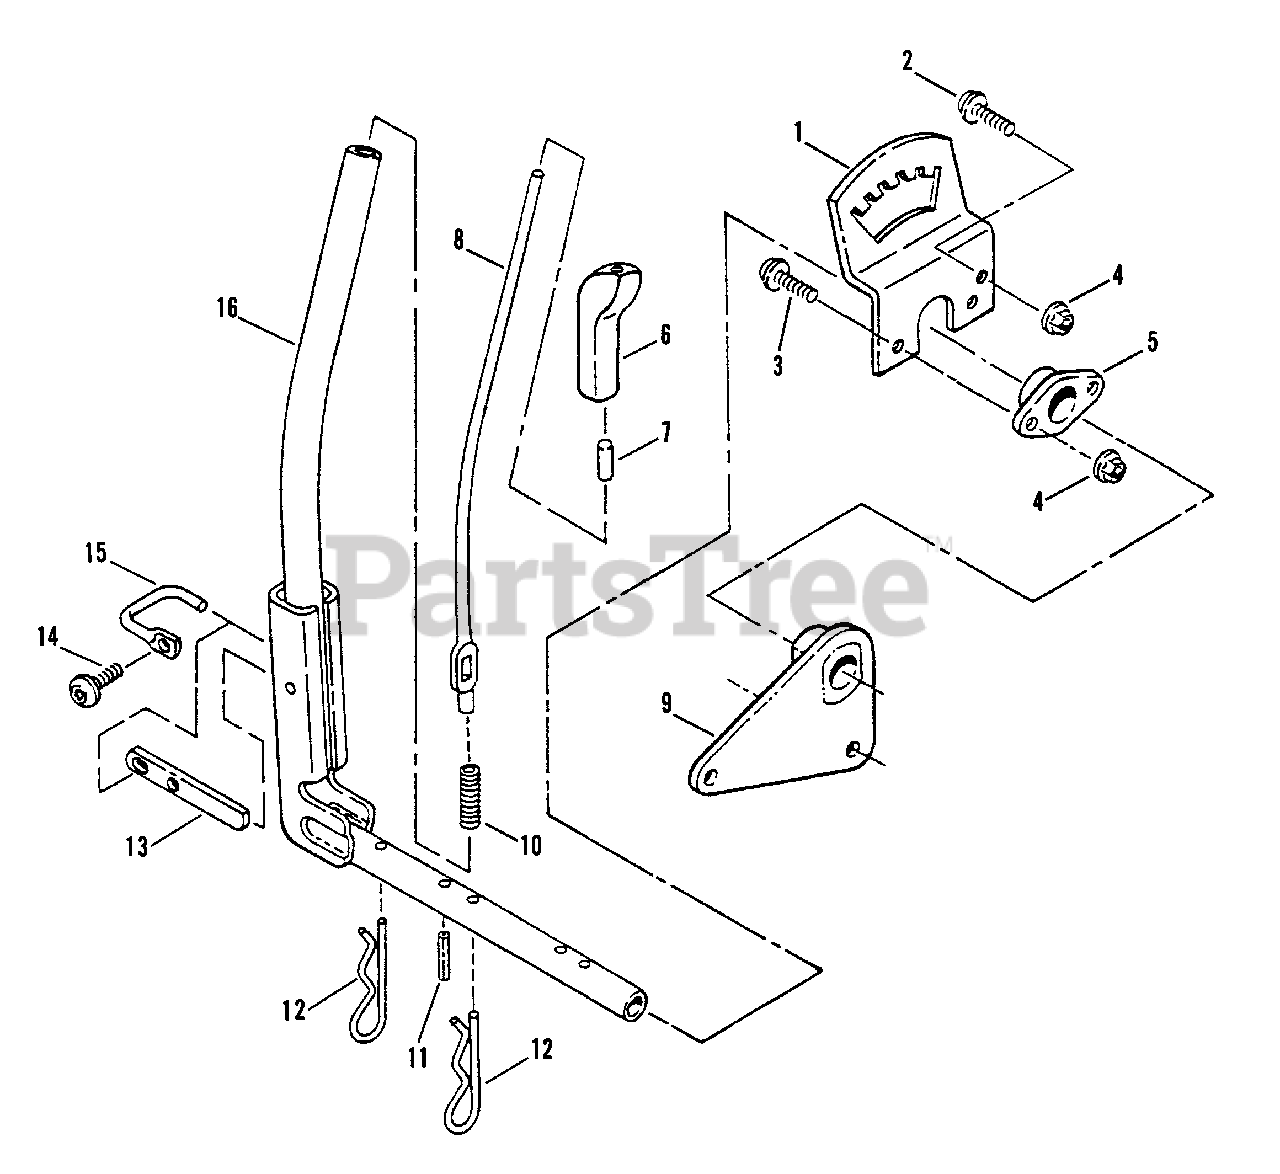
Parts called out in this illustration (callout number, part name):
1	QUADRANT, Lift Lever
2	SCREW, 5/16-18 x 5/8" Truss Head (Torx)
3	SCREW, 5/16-18 x 7/8" Truss Head (Torx)
4	NUT, 5/16-18 Hex Flange Lock
5	PIVOT, Lift Lever
6	KNOB, Lift Lever
7	CAP, Lever Rod
8	ROD, Lift Lever
9	BELL-CRANK, Lift Structure
9	BELLCRANK, Lift Structure
11	PIN, 1/4 x 1 1/8" Dowel
12	PIN, 5/32 x 2 5/8" Hair
13	DETENT, Latch
14	SCREW, 1/4-20 x 5/8" Truss Head (Torx)
15	LATCH, Pivot
16	STRUCTURE, Lift Lever
